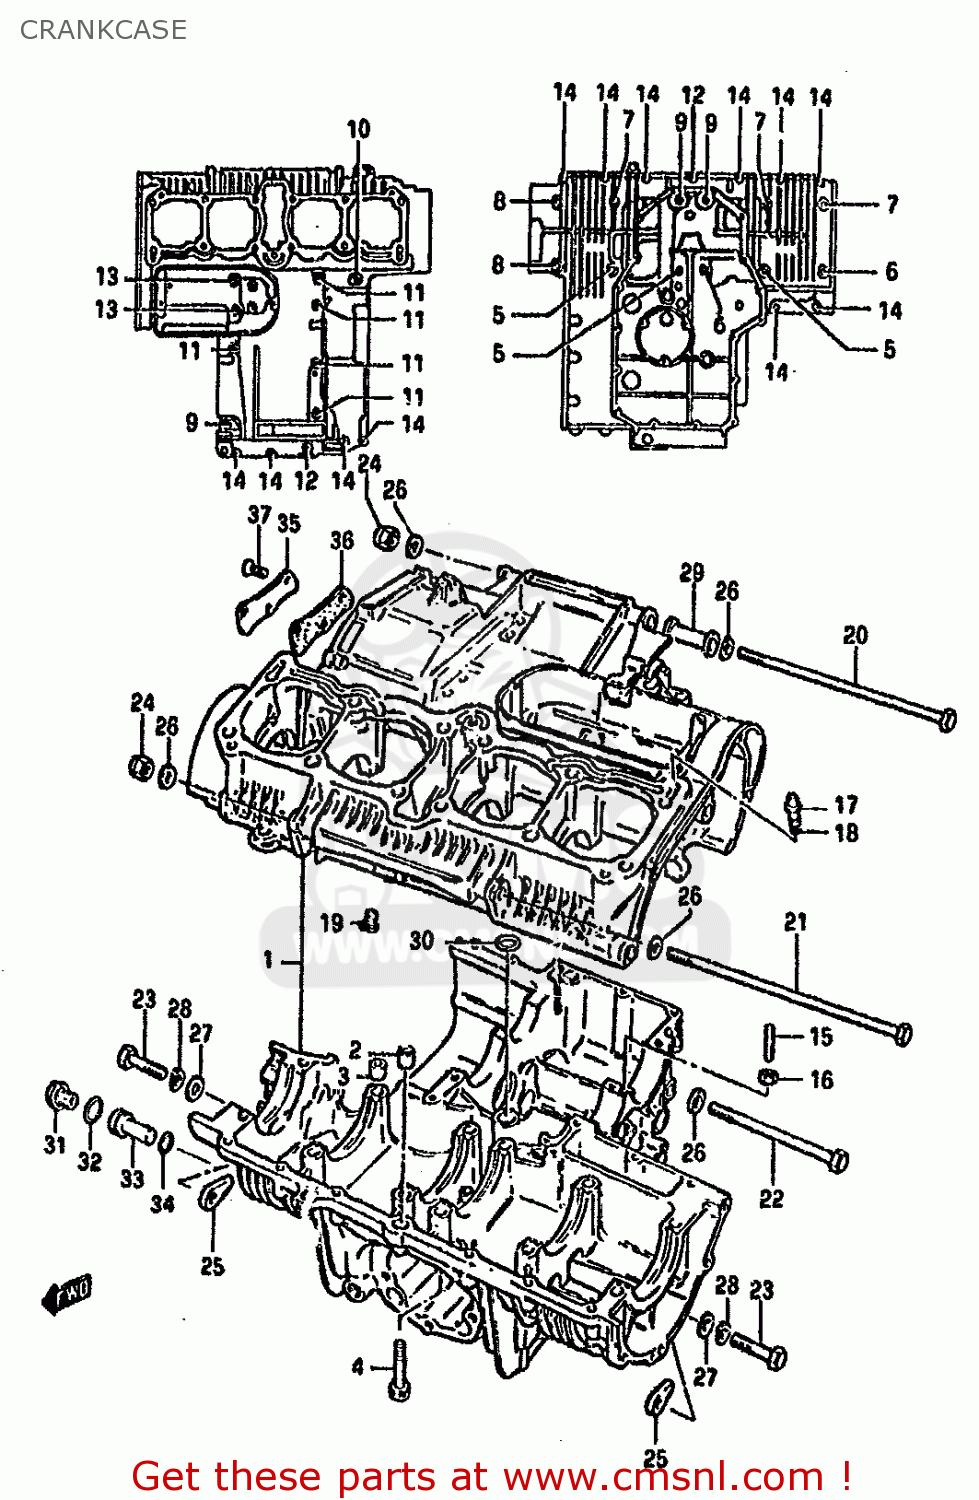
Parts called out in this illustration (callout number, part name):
1	CRANKCASE SET
2	PIN(10.4X13X22)
3	PIN (11X20)(SUS)
4	BOLT
5	BOLT(8X140)
6	BOLT
7	BOLT (8X95)
8	BOLT (8X70)
9	BOLT 8X65
10	BOLT 6X95
11	BOLT (6X80)
12	BOLT (6X60)
13	BOLT,UNDER
14	BOLT
15	STUD BOLT
16	NUT
17	JET
18	O RING(D:1.05,ID:3.1)
19	JET,AIR
20	BOLT(10X225)
21	BOLT(10X250)
22	BOLT(10X165)
23	BOLT 10X60
24	NUT
25	NUT
26	WASHER
27	WASHER(10.5X20X3.2)
28	LOCK WASHER
29	SPACER
30	O RING(D:3.2,ID:12.9)
31	PLUG
32	O RING(D:2.4,ID:17.8)
33	PIN,OIL GALLERY
34	SEAL (D:1.9 ID:9.8)
35	CAP,OIL GALLERY
36	GASKET,OIL GALLERY (MCA)
37	SCREW
